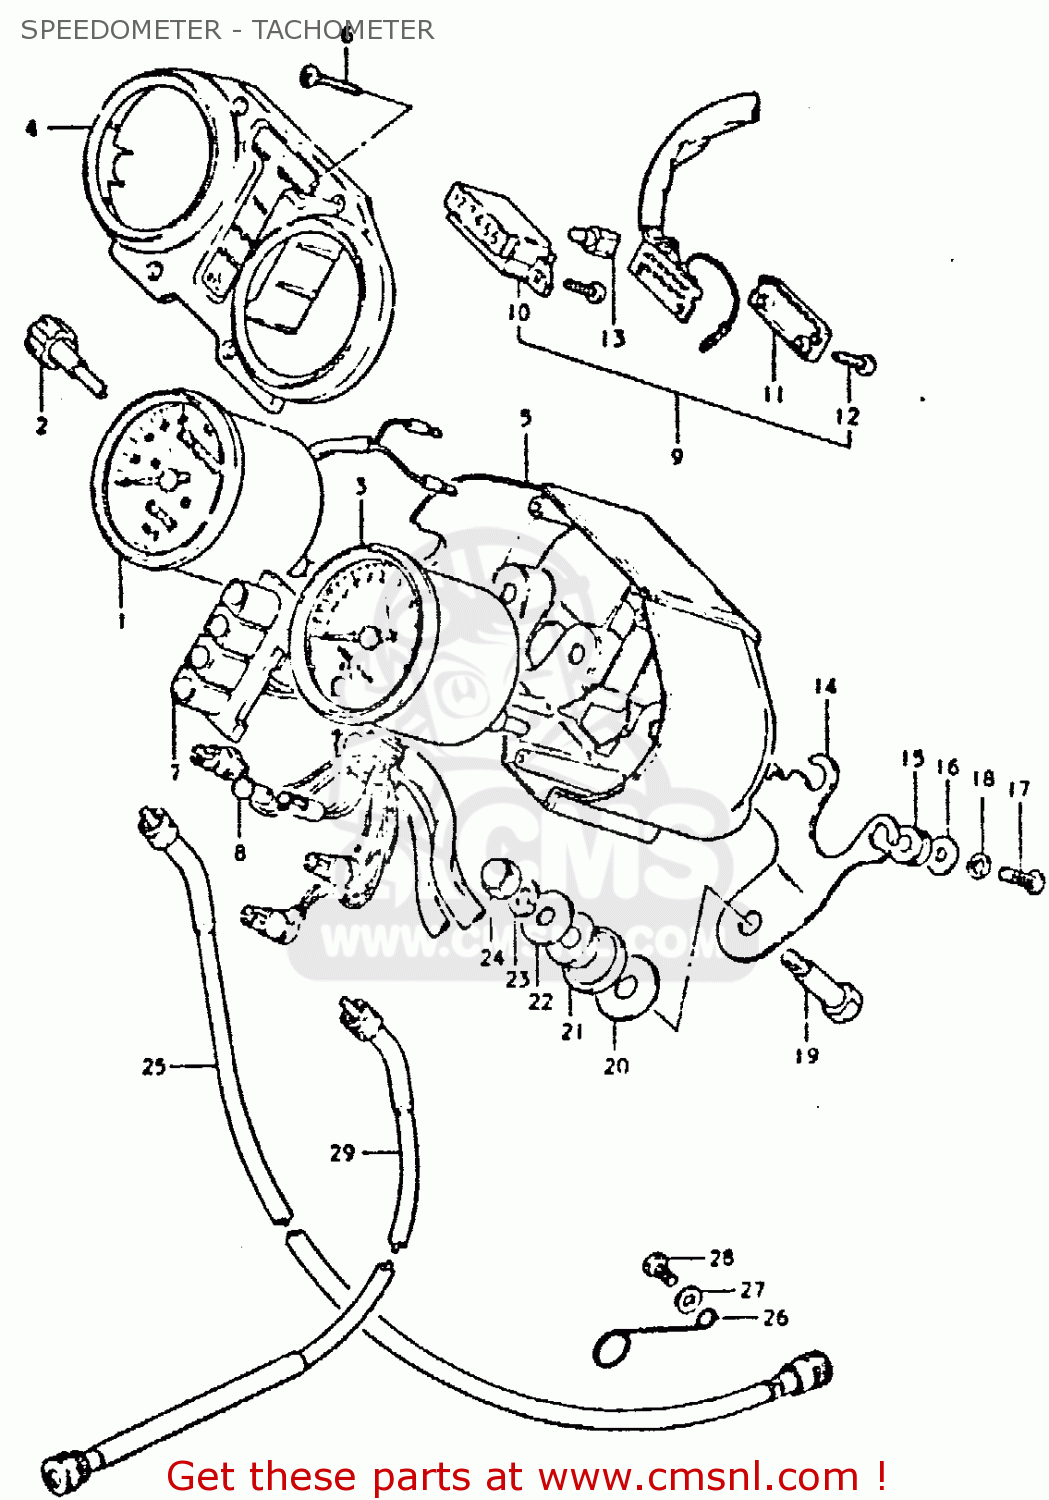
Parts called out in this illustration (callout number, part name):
1	METER,SPEEDOMETER (KM/MPH)
2	KNOB,TRIP METER
3	TACHOMETER
4	CASE,METER,UPPER
5	VISOR,LWR
6	SCREW
7	SOCKET,SPEEDOMETER
8	BULB(12V3.4W,T10)
9	INDICATOR ASSEMBLY,GEAR POSITION
10	CASE,GEAR INDICATOR
11	COVER,LWR
12	SCREW,GEAR INDICATOR
13	BULB(14V1.12W)
14	BRACKET,METER
15	CUSHION
16	WASHER,METER
17	SCREW
18	LOCK WASHER
19	BOLT
20	WASHER
21	CUSHION,METER
22	WASHER(8.5X23X1.2)
23	LOCK WASHER
24	NUT
25	CABLE ASSEMBLY,SPEEDOMETER
26	CLAMP,SPEEDOMETER CABLE
27	WASHER
28	BOLT, UPPER
29	CABLE, TACHOMETER
